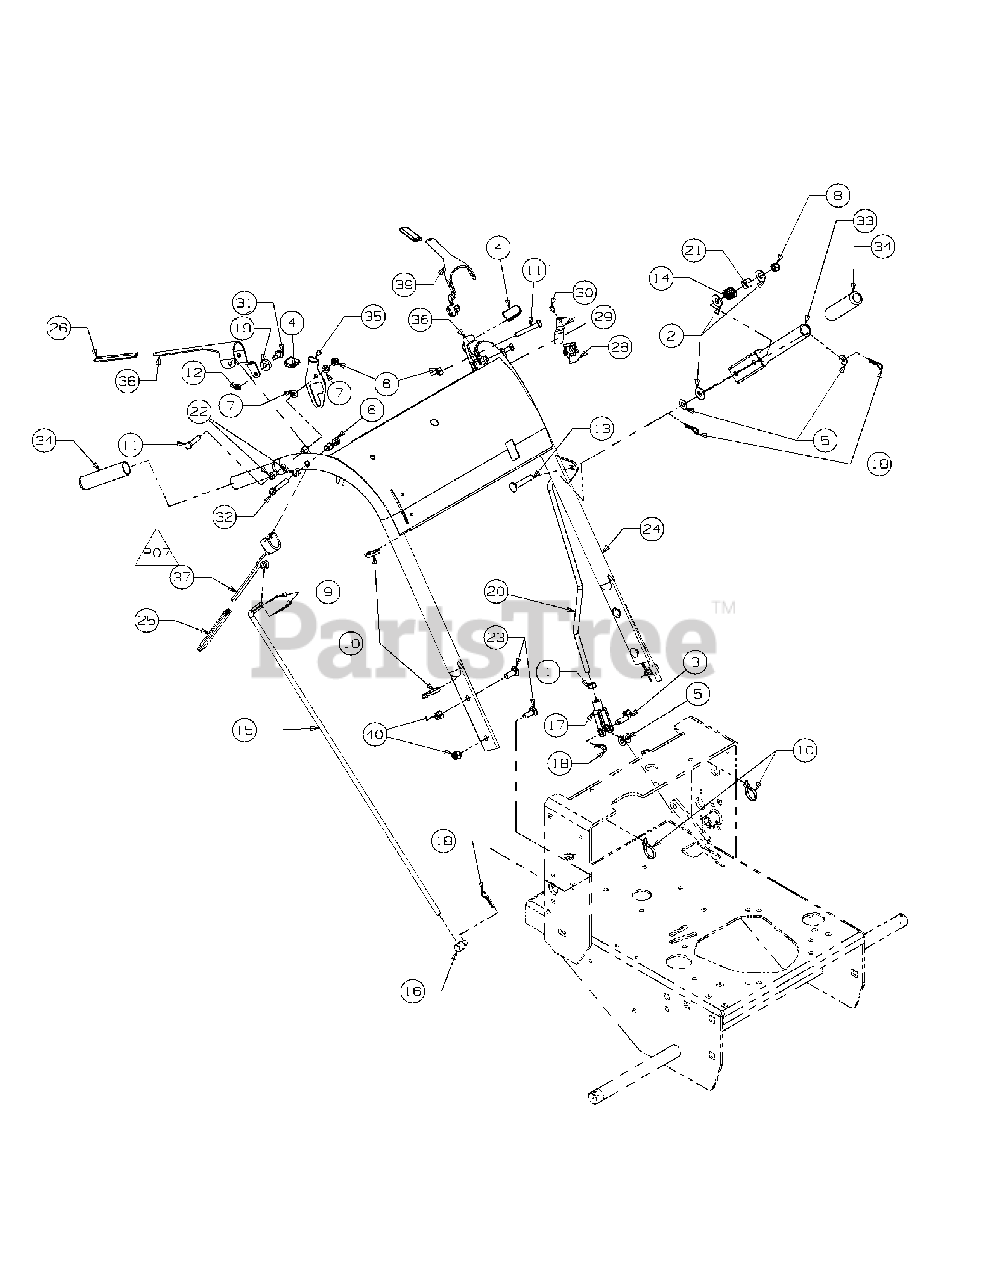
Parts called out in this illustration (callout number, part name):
1	Hex Nut, 3/8-16
2	Flat Washer, 3/8 Zinc 3
3	Clevis Pin, 3/8 x 1-1/8 Zinc
4	Grip, Neutral Latch, 1.25"
5	Flat Washer, 3/8 Zinc
6	Nylock Nut, 5/16-18
7	Flat Washer, 5/16 Zinc
8	Lock Nut, Nylon Insert, 3/8-16
9	Cotter Pin, 3/32 x 3/4, Zinc
10	Cable Tie, 3/16 x .05 x 7.4
11	Hex Cap Screw, 5/16-18 x 2
12	Lock Nut, Nylon Insert
13	Carriage Bolt, 3/8-16 x 2
14	Spring, .850 OD x 1
15	Steering Control Rod
16	Joint Swivel
17	Yoke, 3/8-16 Female
18	Hair Pin 3/8-1/2
19	Control Rod, Hydro Spacer
20	Blade Clutch Rod
21	Spring Sleeve
22	Nylon Bushing
23	Carriage Bolt, 3/8-16 x 1-1/4
24	Handle Assembly
25	Control Sleeve, Black
26	Operator Control Sleeve, Yellow
28	Switch Mounting Snap
29	Operator Presence Return Spring
30	Hex Index Washer Screw, 0.500 2
31	Shoulder Screw, .38 x .412, 1/4-28
32	Hex Cap Screw, 5/16-18, 2.00
33	Blade Clutch Lever
34	Handle Grip, Black, 1" 3
35	Neutral Latch, Right Hand
36	Neutral Latch, Left Hand
37	Lever Assembly Control
38	Operator Presence Control RH
39	Operator Presence Control LH
40	Lock Nut, Nylon Insert, 3/8-16
